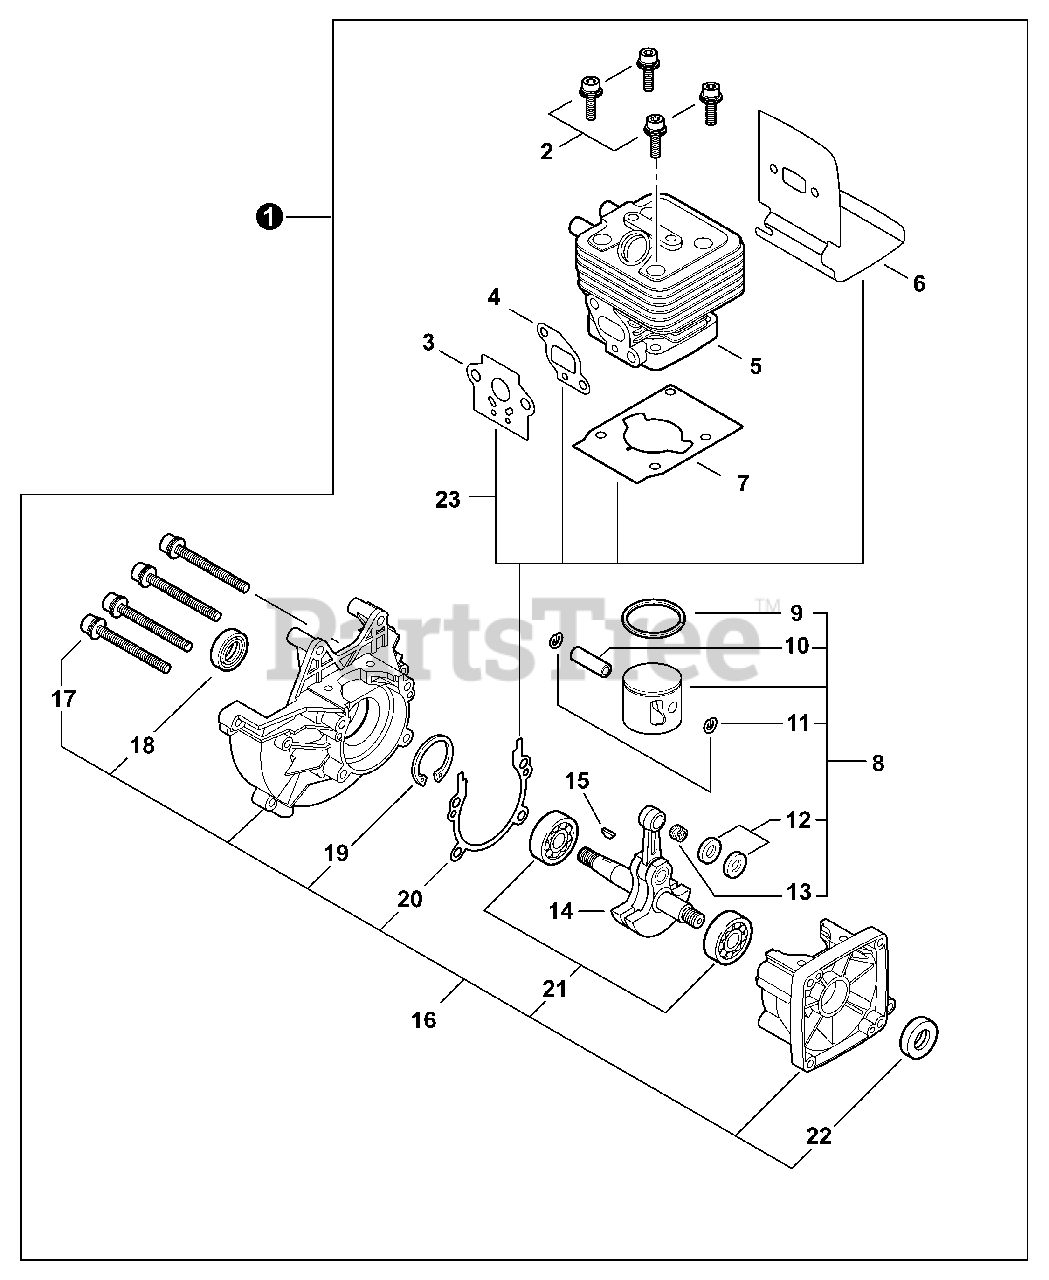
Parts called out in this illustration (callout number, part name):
1	SHORT BLOCK
2	SCREW 5×25
3	GASKET, INTAKE
4	GASKET, INTAKE
5	CYLINDER
6	HEAT SHIELD, EXHAUST
7	GASKET, CYLINDER
8	PISTON KIT
9	RING, PISTON
10	PIN, PISTON 6×9×27.8
11	RING, SNAP
12	WASHER, THRUST
13	BEARING, NEEDLE 9
14	CRANKSHAFT ASSY
15	KEY, WOODRUFF
16	CRANKCASE KIT
17	BOLT 5×28
18	SEAL, OIL
19	RING, SNAP 32
20	GASKET, CRANKCASE
21	BEARING, BALL 6201
22	SEAL, OIL 12
23	GASKET KIT - REPOWER
